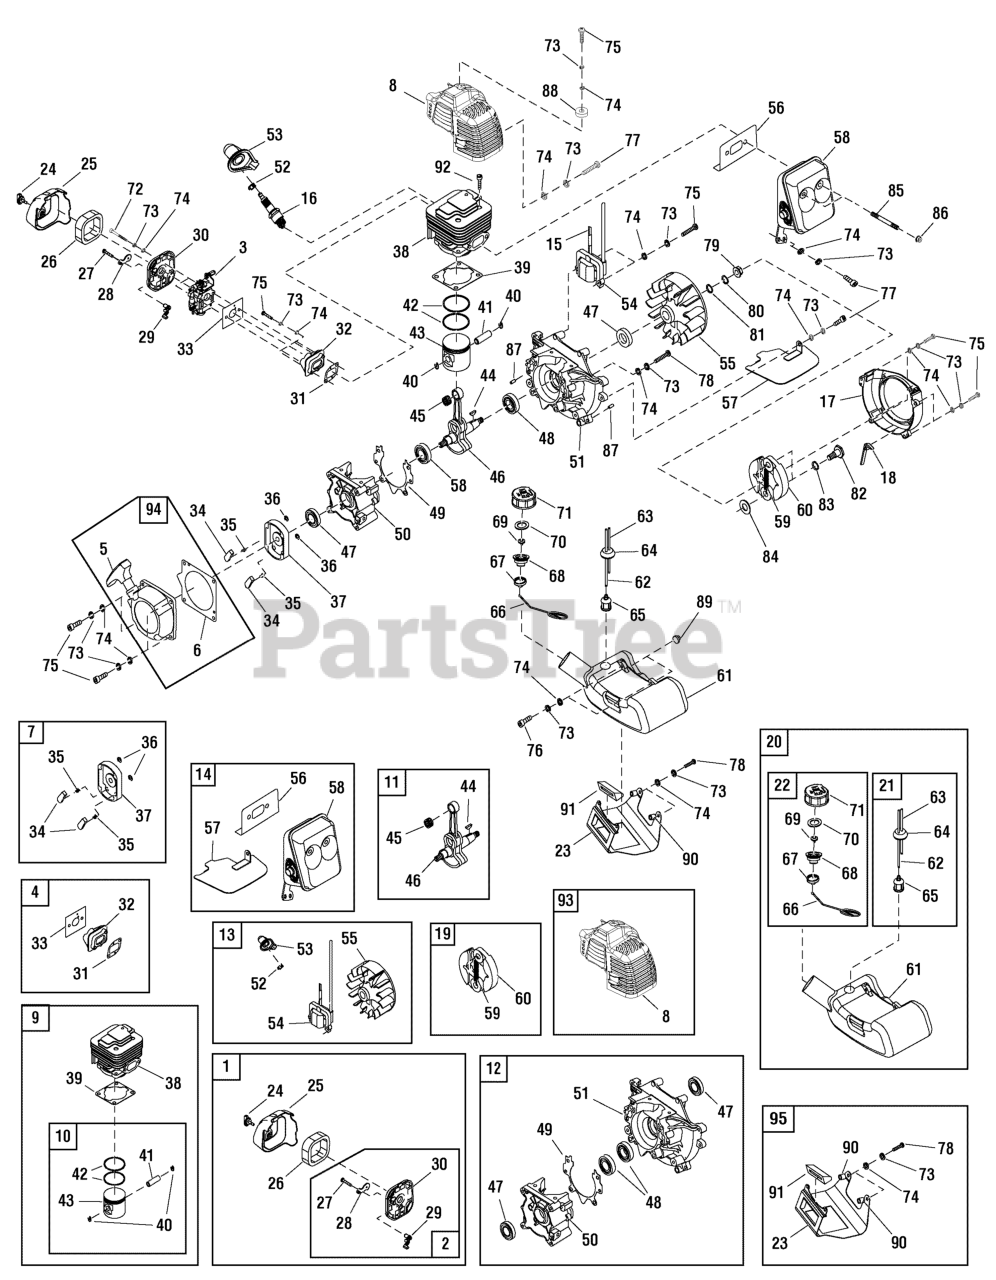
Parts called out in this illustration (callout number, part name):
1	KIT, Air Cleaner Assembly, Complete
2	KIT, Air Cleaner Assembly, Inner
3	CARBURETOR
4	KIT, Admitting Pipe Assembly
5	STARTER, Rewind
6	PAD, Starter
7	KIT, Start Reel Assembly
8	SHROUD
9	KIT, Cylinder Assembly
10	KIT, Piston Assembly
11	KIT, Crank Shaft Assembly
12	KIT, Cylinder Case Assembly
13	KIT, Magneto Assembly
14	KIT, Muffler Assembly
16	SPARK PLUG
17	COVER, Fan
18	FLASH PAN
19	KIT, Expander Assembly
20	KIT, Fuel Tank Assembly
21	KIT, Fuel Line Assembly
22	KIT, Fuel Cap Assembly
23	BRACKET, Tank
25	COVER, Cleaner, Outer
26	FILTER
27	SCREW, Self Tapping, ST4.2 x 12
28	CHOKE VALVE
29	HANDLE, Choke Valve
30	COVER, Cleaner, Inner
31	GASKET, Admitting Pipe
32	ADMITTING PIPE
33	GASKET, Carburetor
34	STARTER CINCH
35	SPRING, Starter
36	RING, Retainer
37	STARTER BOX
38	CYLINDER
39	GASKET, Cylinder
40	RING, Pin Retain
41	PIN, Piston
42	RING, Piston
43	PISTON
44	KEY, 3 x 5 x 13
45	BEARING, Needle
46	CRANKSHAFT
47	SEAL, Oil, 11.7 x 22 x 7
48	BEARING, 6201/P6
49	GASKET, Crank Case
50	CRANK CASE, Rear
51	CRANK CASE, Front
52	CLIP, Spark Plug
53	BOOT, Spark Pin
54	MAGNETO COIL
55	FLY WHEEL
56	GASKET, Muffler
57	CLAPBOARD
58	MUFFLER
59	SPRING, Extension
60	EXPANDER, Complete
61	TANK, Fuel
62	PIPE, Fuel
63	PIPE, Soft PVC
64	PLUG, Fuel Line
65	FILTER, Fuel
66	CHAIN
67	COVER, End
68	LID, Fuel Tank, Inner
69	IINLET
70	GASKET
71	LID, Fuel Tank
72	BOLT, M5 x 50
73	WASHER, Spring, 5
74	WASHER, Flat, 5
75	BOLT, M5 x 20
76	BOLT, M5 x 16
77	BOLT, M5 x 12
78	BOLT, M5 x 30
79	NUT, M8
80	WASHER, Spring, 8
81	WASHER, Flat, 8
82	SCREW, Shaft
83	WASHER, Wave
84	WASHER, B
85	BOLT, Muffler
86	NUT, M5
87	PIN, Cylindrical, B4 x 10
88	GASKET
89	PLUG, Rubber
90	PAD, Bracket
91	COVER, Rubber
92	BOLT, M5 x 18
93	KIT, Shroud Assembly
94	KIT, Starter Assembly
95	KIT, Tank Bracket
